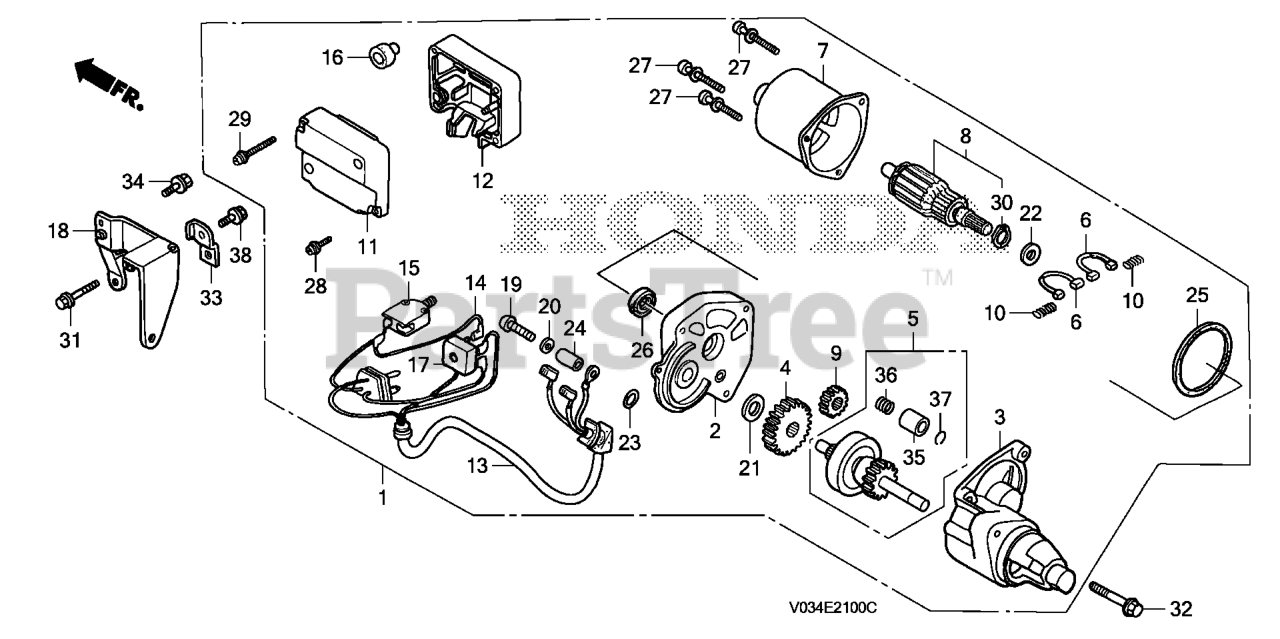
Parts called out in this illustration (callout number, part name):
1	STARTER MOTOR UNIT (AC)
2	HOUSING, CENTER Use from Engine SN 2056820.
3	HOUSING, PINION
4	GEAR, REDUCTION
5	CLUTCH Use from Engine SN 1171449.
6	BRUSH Use from Engine SN 2056820.
7	YOKE
9	GEAR, DRIVE Use up to Engine SN 2056819.
10	SPRING, BRUSH RETURN Use from Engine SN 2056820.
11	COVER Use from Engine SN 2056820.
12	CASE Use from Engine SN 2056820.
13	WIRE Use from Engine SN 2056820.
14	SUB-WIRE Use up to Engine SN 2056819.
15	SWITCH, STARTER (Honda Code 2299584). (A.C. 380V-16A)
15	SWITCH, STARTER (Honda Code 2773141). (A.C. 250V-16A)
16	CAP Use up to Engine SN 2056819.
17	DIODE Use up to Engine SN 2056819.
18	BRACKET, SWITCH BOX
19	SCREW, TRUSS (4X30) Use from Engine SN 2056820.
20	WASHER, STAR (4MM) Use from Engine SN 2056820.
21	WASHER (A) Use from Engine SN 2056820.
22	WASHER (B) Use from Engine SN 2056820.
23	O-RING Use from Engine SN 2056820.
24	COLLAR Use from Engine SN 2056820.
25	GASKET Use from Engine SN 2056820.
26	OIL SEAL Use up to Engine SN 2056819.
27	SCREW-WASHER (5X30) Use up to Engine SN 2056819.
28	SCREW-WASHER (4X20)
29	SCREW-WASHER (4X30)
30	CIRCLIP (OUTER) (12MM) Use up to Engine SN 2056819.
31	BOLT, FLANGE (6X40)
32	BOLT, FLANGE (8X35)
33	BASE, CLIP
34	BOLT, FLANGE (6X12) (CT200)
35	STOPPER, PINION Use from Engine SN 2056820.
36	SPRING, COIL
37	RING, RETAINING Use from Engine SN 2056820.
38	BOLT, FLANGE (6X12) (CT200)
